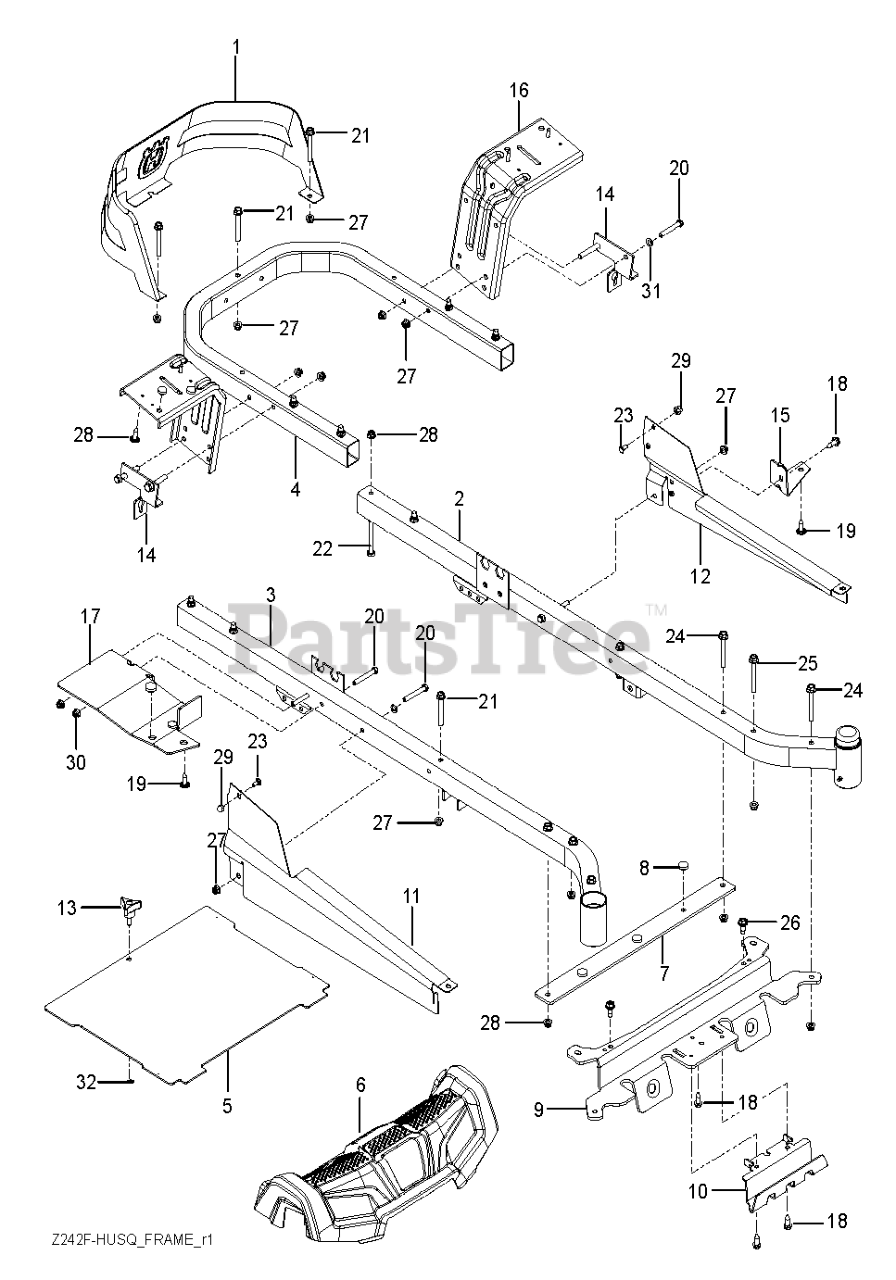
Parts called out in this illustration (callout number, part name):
1	GUARD.ENGINE.HUSQ.RZ.X498
2	FRAME.TUBE.RZ.MAIN.WELD.RH.ORG
3	FRAME.TUBE.RZ.MAIN.WELD.LH.ORG
4	TUBE.PNT.FRAME.RER.HUSQ.23".RZ
5	PLATE, FOOT W/DECALS RZ
6	COVER.FOOTREST.REFRESH.ASM
7	FOOTREST.PLATE.SUPPORT.X431
8	GROMMET.BUMPER
9	CROSS.PNT.MEMBER.BLK
10	SKID.PLATE.PNT.RZ.REF.SIVER
11	COVER.RAIL.RH.RZ.X668
12	COVER.RAIL.LH.RZ.X668
13	KNOB W/STUD
14	BRKT ROD.BYPASS.EZT.X431
15	SUPPORT.PNT.LH.CONSOLE.FRONT
16	FENDER.SUPPORT.PNT.X431
17	SUPPORT.PNT.RH.CONSOLE.FRONT
18	BOLT.5/16HEX.WHS.HD
19	SCREW.#10 X 0.750.BOS
20	BOLT.FIN HEX 5/16-18UNC X2 1/4
21	BOLT HEX 5/16-18 GR 5
22	BOLT.HEX.FIN.3/8-16 X 3.GR5
23	BOLT.CARRIAGE.5/16-18.7/16
24	HHFS 3/8-16 X 3 GRD 5 ZD
25	BOLT SHOULDER,FLANGED,3/8-16X3
26	BOLT.5/16-18.THRD.ROLL.SHOULDR
27	5/16-18 NYLOC FLANGE NUT
28	NUT 3/8-16 HEX FLG NYLOC ZD
29	NUT ACORN,FLANGED,5/16-18
30	NUT LOCK HEX FLANGE 5/16-18
31	WASHER
32	WASHER 5/16"
